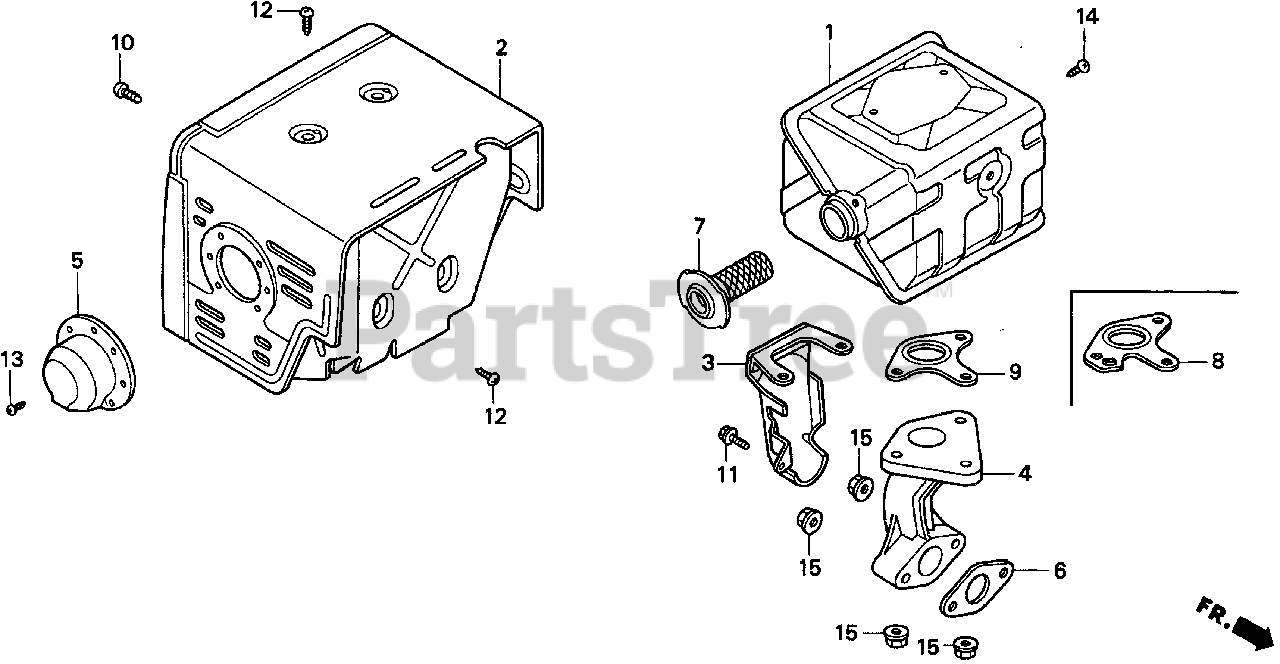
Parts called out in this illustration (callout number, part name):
1	MUFFLER (100DB) (SILENT)
1	MUFFLER (100DB)
2	PROTECTOR, MUFFLER
4	PIPE, EX.
6	GASKET, EX. PIPE
6	GASKET, EX. PIPE (WACKER)
7	ARRESTER, SPARK
8	GASKET, MUFFLER (ARRESTER)
9	GASKET, MUFFLER
10	SCREW, TAPPING (6X10)
12	SCREW, TAPPING (5X8)
14	SCREW, TAPPING (4X6)
15	NUT, FLANGE (8MM)
